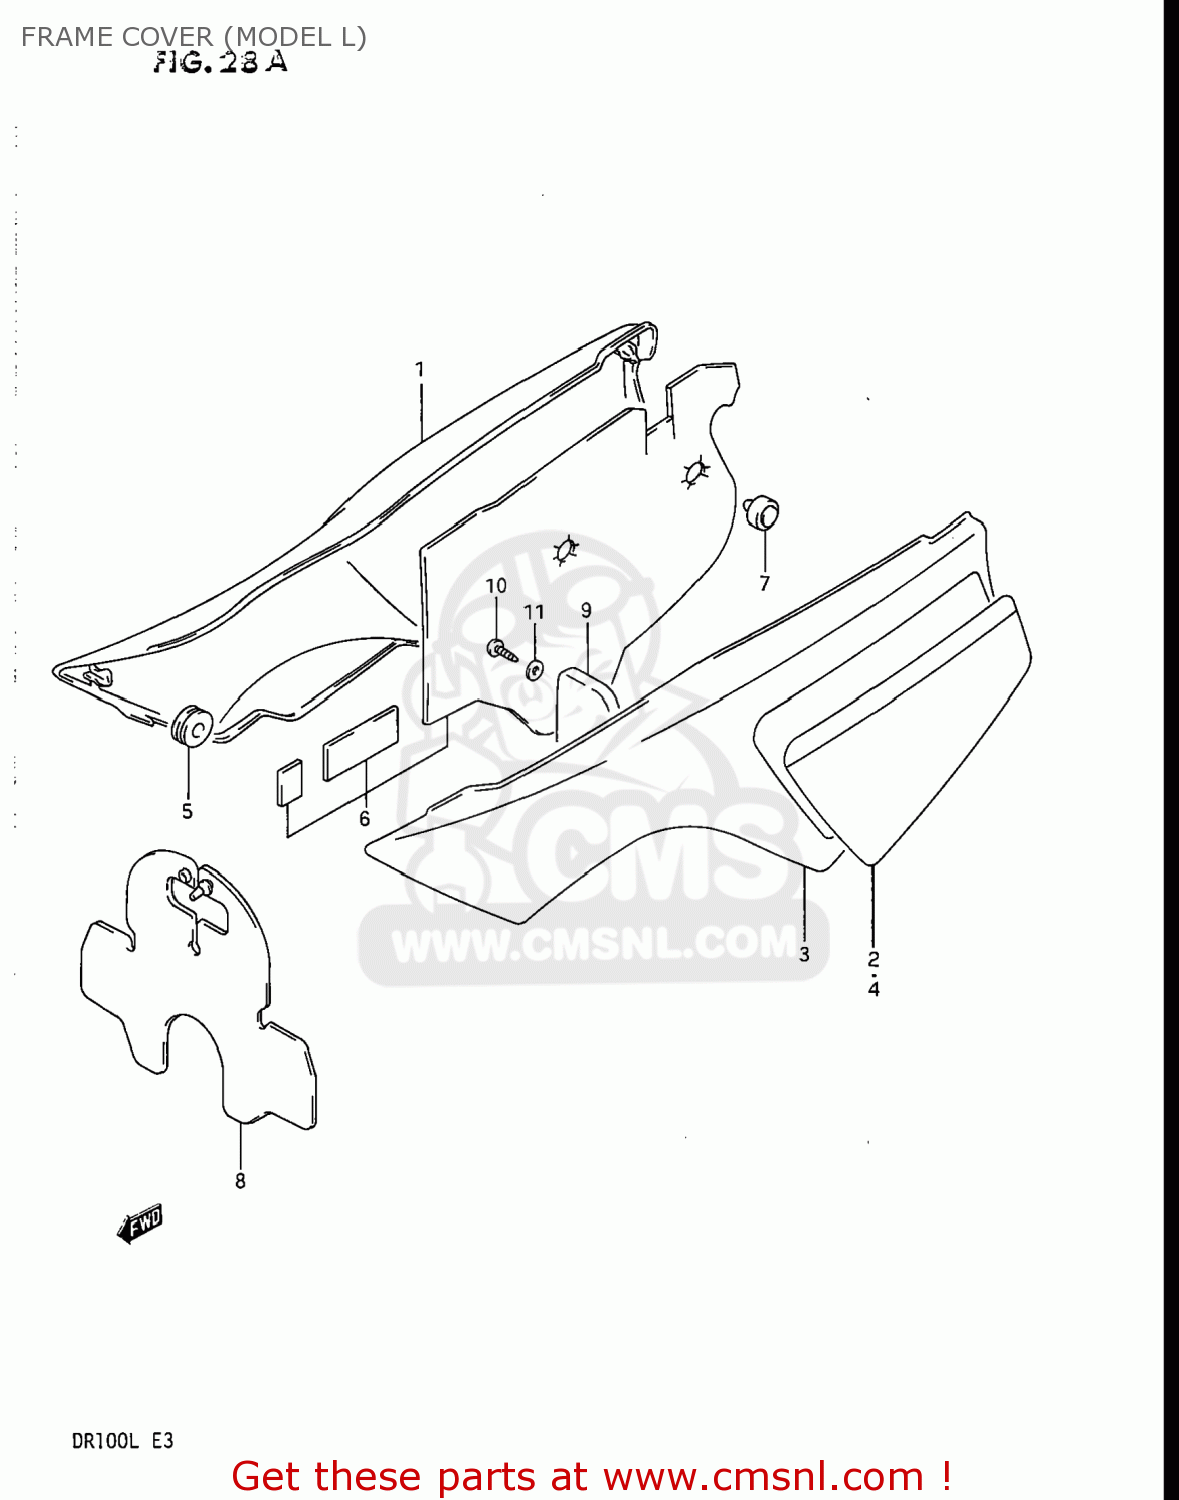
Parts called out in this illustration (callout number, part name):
1	COVER,FRAME,RIGHT
2	TAPE,FRAME COVER,RIGHT
3	COVER,FRAME,LEFT
4	TAPE,FRAME COVER,LEFT
5	CUSHION
6	HEAT SHIELD SET,FRAME
7	CUSHION
8	MUD FLAP,FRONT
9	MUD GUARD,AIR CLEANER
10	SCREW
11	WASHER 4MM
